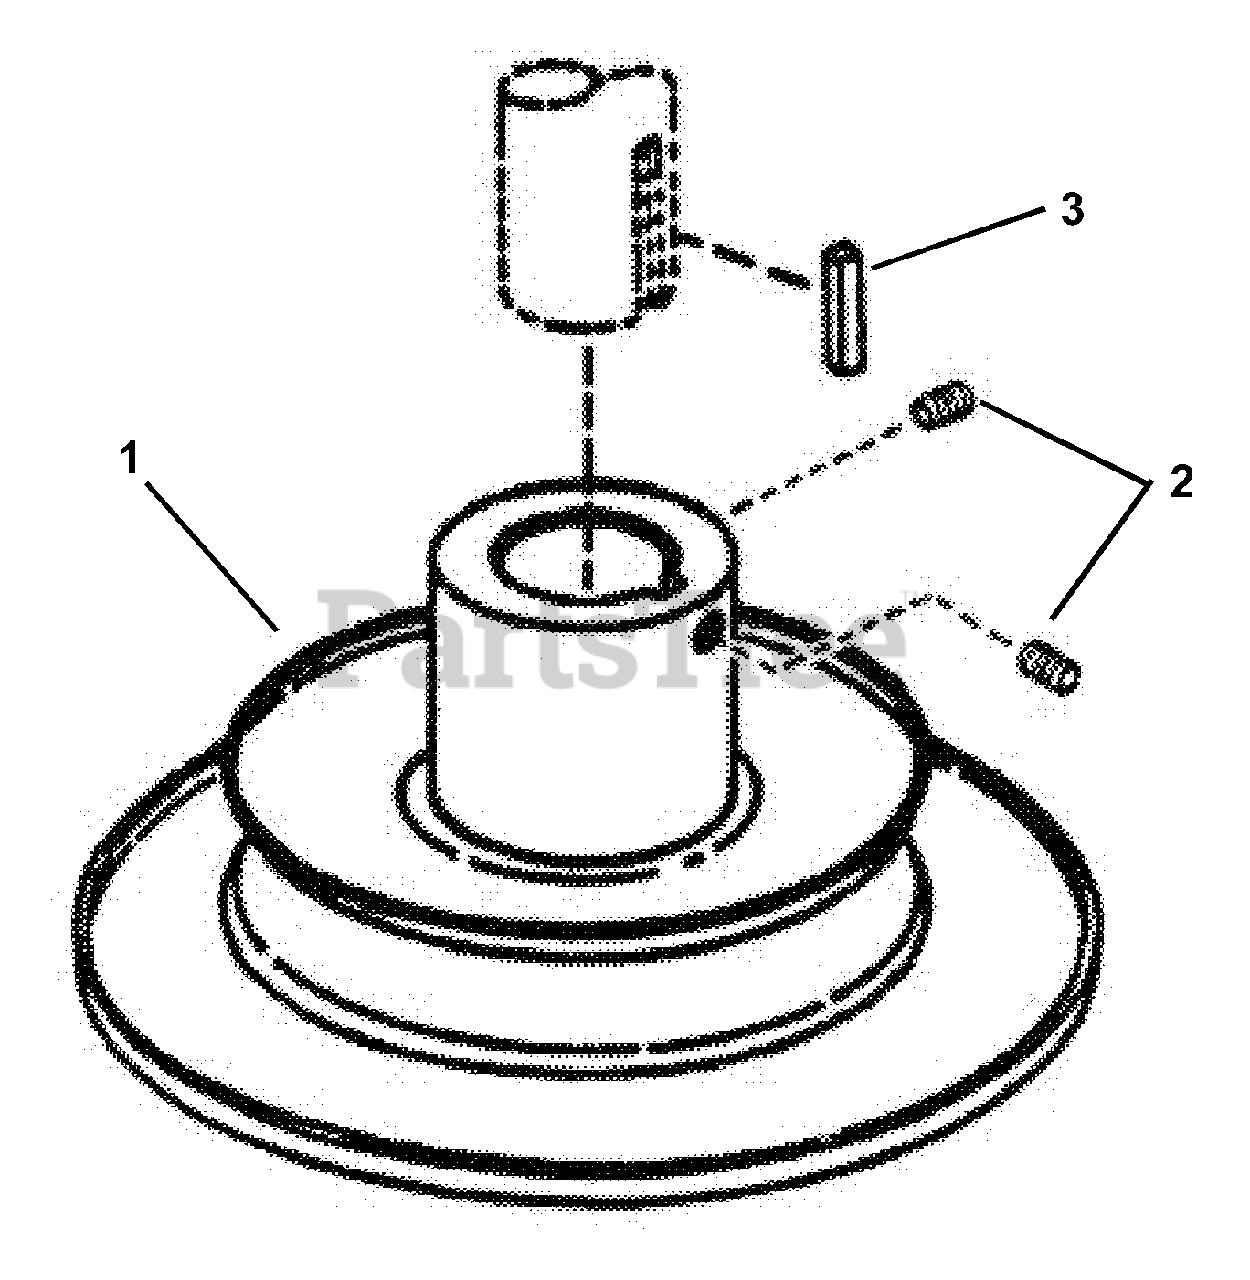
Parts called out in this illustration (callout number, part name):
1	WELDMENT, 5.25" O.D. Drive Disc
2	SCREW, 3/8-16 x 3/8" Set
3	KEY, 1/4" Square x 2"
